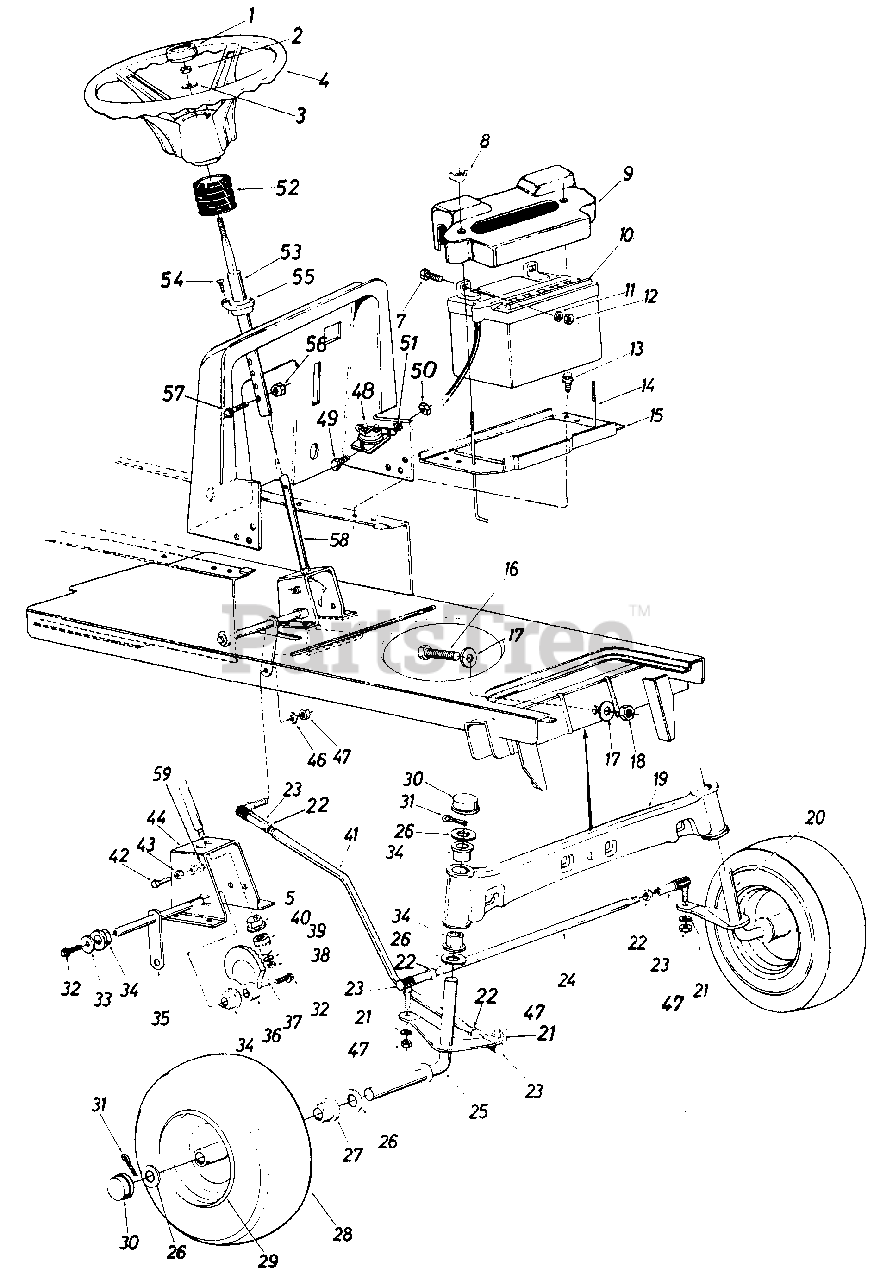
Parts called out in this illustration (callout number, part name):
1	Steering Wheel Cap
2	Hex Cent. L-Nut 5/16-24 Thd.
3	Bell-Wash. 5/16" I.D. x .87" O.D. x .060
4	Steering Wheel
5	Plastic Hex Bearing 5/8" I.D.
7	Hex Bolt 1/4-20 x .62" Lg.
8	Wing Nut Plastic 1/4-20 Thd.
9	Battery Cover
10	12-V Battery
11	L-Wash. 1/4" I.D.
12	Hex Nut 1/4-20 Thd.
13	Hex Thd. Rolling Scr '/4-20 x .50 Lg
14	Battery Hold Down Rod
15	Battery Plate
16	Hex Bolt 5/8-18 x 2.5" Lg.
17	Flat Wash. .66" I.D. x 2.25" O.D. x .17
18	Hex Cent. L-Nut 5/8-18 Thd.
19	Front Pivot Bar Ass'y.
20	Front Axle Ass'y.-L.H.
21	L-Wash. 3/8" I.D.
22	Hex Jam Nut 3/8-24 Thd.
23	Ball Joint Ass'y.
24	Tie Rod
25	Front Axle Ass'y.-R.H.
26	Fl-Wash. .780 I.D. x 1.59 O.D.
27	Flange Bearing
28	Front Wheel Ass'y. Comp.
29	Front Wheel Rim Only
30	Dust Cover
31	Cotter Pin 5/32" Dia. x 1.00" Lg.
32	Hex Bolt 3/8-24 x .75" Lg. Grade 5
33	Fl-Wash. 3/8 I.D. x 1.25 O.D. x .090
34	Flange Double "D" Brg. .753 I.D.
35	Steering Arm Shaft Ass'y.
36	Side Gear-Steering
37	Bell-Wash. 3/8" I.D.
38	Hex Cent. L-Nut 5/16-24 Thd.
39	Fl-Wash. 5/16" I.D. x .62 O.D. x .059
40	Pinion Gear-Steering
41	Drag Link
42	Hex Bolt 3/8-16 x 1.25" Lg.
43	Hex Nut 3/8-16 Thd.*
44	Steering Gear Sup. Ass'y.
46	L-Wash. 3/8" I.D.
47	Hex Nut 3/8-24 Thd.
48	Solenoid
49	Hex Bolt 1/4-20 x .5" Lg.
50	Hex Sems Nut 1/4-20 Thd.
51	Ext. L-Wash. 1/4" I.D.
52	Steering Bellow
53	Upper Steering Shaft
54	Oval Hd. Cr.-Sunk Scr. #10 x 5/8" Lg.
55	Fl-Bearing .89" I.D. x 1.36" O.D.
56	Hex L-Nut 1/4-20 Thd.
57	Hex Bolt 1/4-20 x 1.25" Lg.
58	Lower Steering Shaft
59	Nylon Cap
